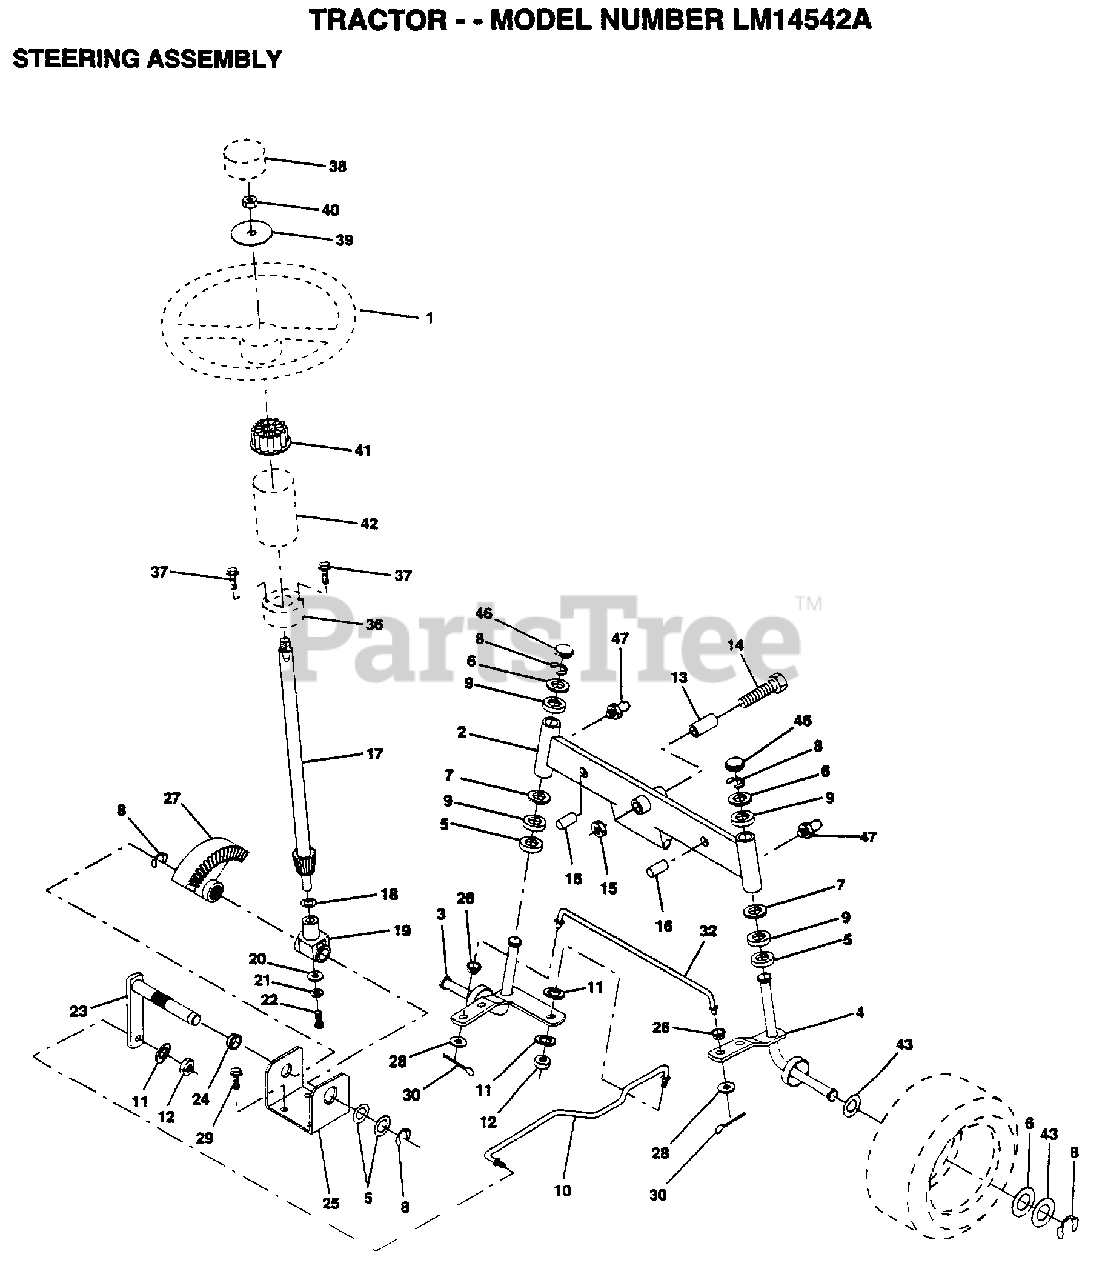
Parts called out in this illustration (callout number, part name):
2	AXLE ASM FRONT
3	SPINDLE LH
4	SPINDLE RH
5	WASHER .T
6	WASHER
7	WASHER
8	RING
9	COL. SRTG. BEAR.
11	LOCKWASHER
13	BEARING
14	BOLT HEX 5/8-11
15	"NUT-LOC,FLANGE LT"
16	AXLE PIN
17	SHAFT ASM
18	THRUST WASHER
19	SUPPORT.SHAFT
21	LOCKWASHER
22	"SCREW,SPECIAL"
24	NYLINER T
25	"BRKT,STEERING"
26	BUSHING.DRAGLINK
27	GEAR SECTOR
28	WASHER
29	SCREW
30	COTTER PIN
32	TIE ROD
38	ST WHL INSERT CAP
39	WASHER T
40	GRIPCO NUT
41	ADAPTER-WHEEL LT
42	"TUBE, STR SHAFT"
43	WASHER
46	CAP
47	FITTING GREASE
